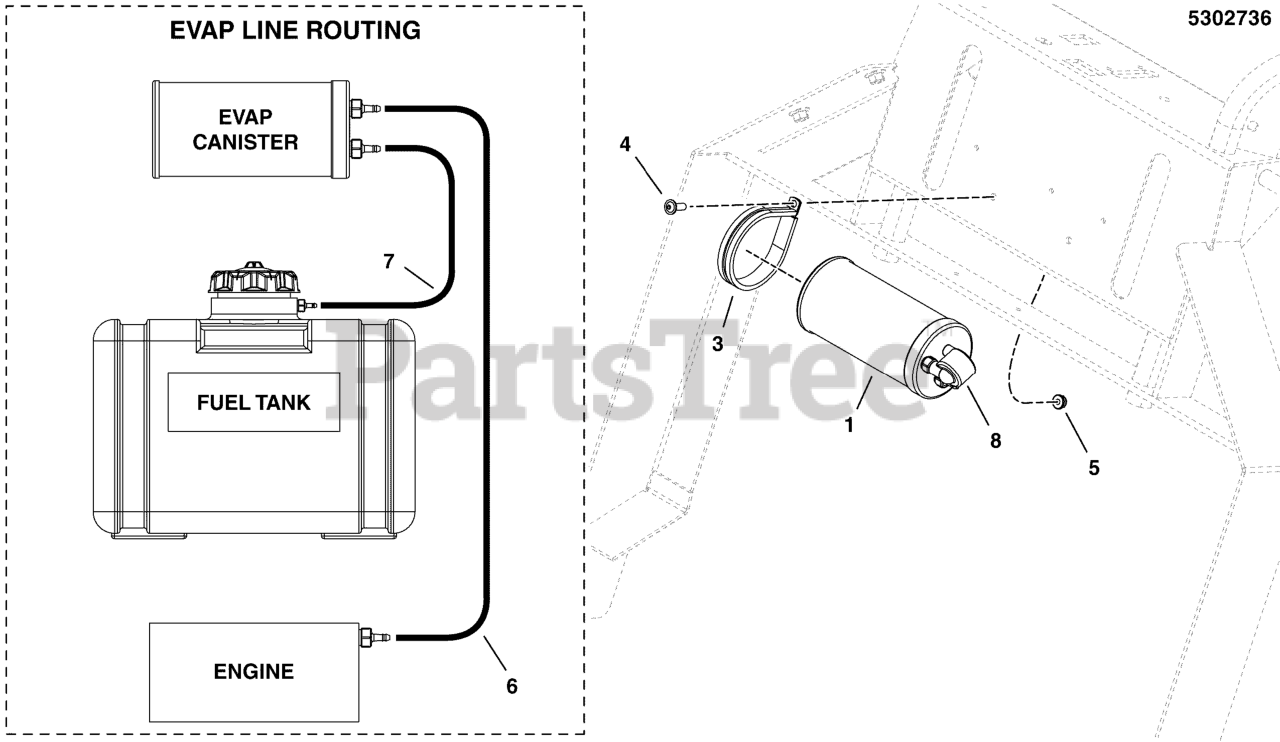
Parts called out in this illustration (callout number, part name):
1	CNSTR, CARB, 6 GAL
2	DECAL, EPA CERT, WALKS
3	CLAMP, 3" ID, CUSHIONED, STAINLESS
5	NUT, 1/4-20 HEX NYLOCK FLANGE
6	HOSE, VAPOR, 5MM ID, 30.00 LG
7	HOSE, VAPOR, 5MM ID, 24.00 LG
8	DUST FILTER, CANISTER
